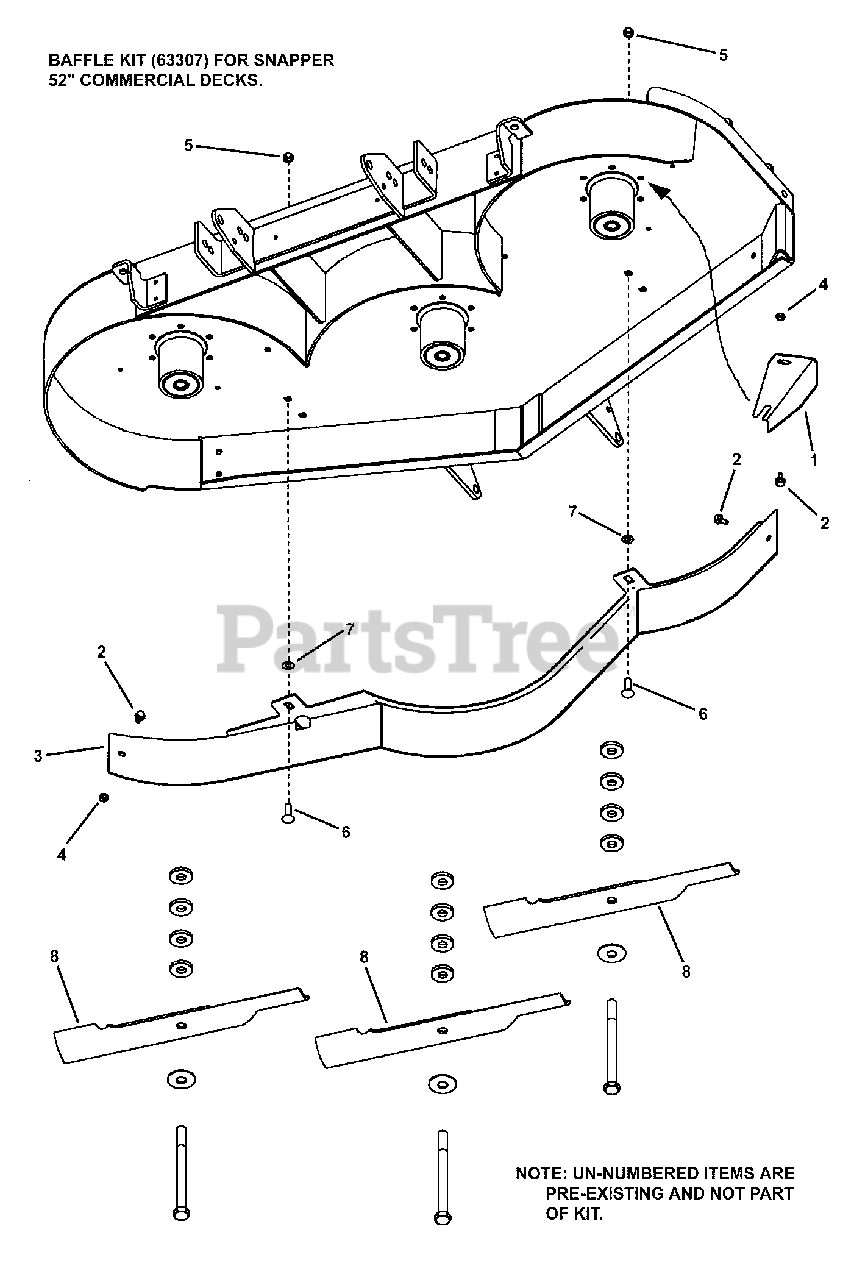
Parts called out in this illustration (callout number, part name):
1	BAFFLE, Discharge, 52" Deck
2	SCREW, 5/16-18 x 5/8" Hex Washer Self-Tap
3	WELDMENT, Baffle, 52" Deck
4	NUT, 5/16-18 Hex Center Lock, GR5 or B
5	NUT, 3/8-16 Hex Center Lock, GR5 or B
6	BOLT, 3/8-16 x 1-1/4" Square Neck Carriage, GR5
7	RETAINER, 3/8" Bolt
8	BLADE, 18" Commercial w/Extra Cut
